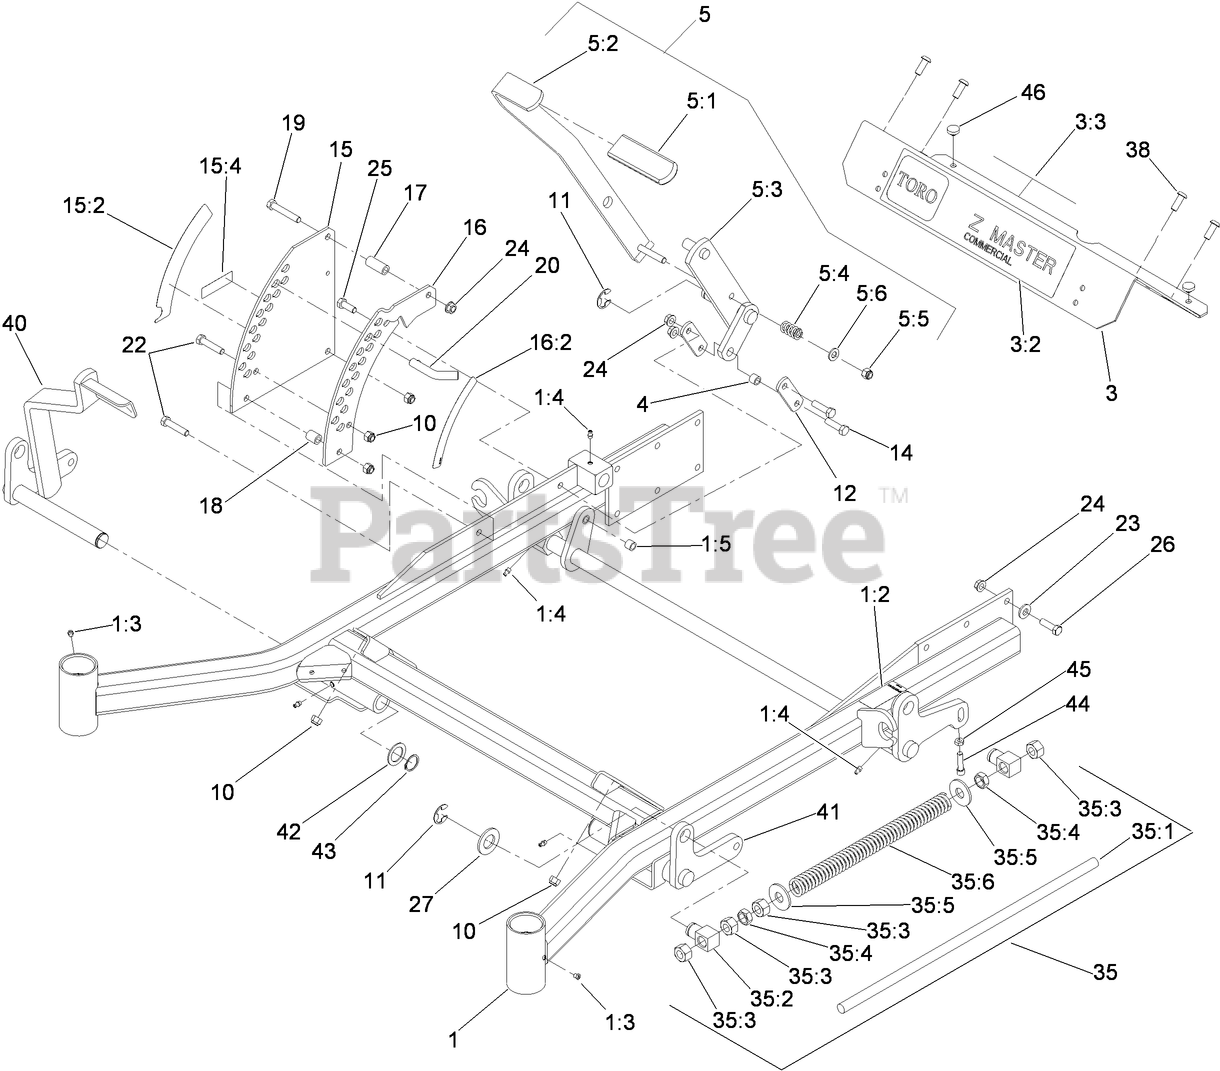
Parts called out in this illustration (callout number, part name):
1	Frame ASM
1:2	Decal-Brake, Parking
1:4	FITTING-GREASE
1:5	Bushing
3	FOOTREST
3:3	DECAL-WARNING
4	Bushing
5	DECK LIFT HANDLE ASM
5:1	GRIP-LEVER, LIFT
5:2	LEVER-LIFT
5:3	ARM-LIFT, DECK
5:4	SPRING-COMPRESSION
5:5	NUT-LOCK, NI
5:6	WASHER-FLAT
10	NUT-LOCK, NI
11	RING-RETAINING, EXT
12	ARM-LIFT, DECK
14	SCREW-HH
15	PLATE-HOC, OUTER
15:2	Decal-Height, Deck
15:4	DECAL-ARRESTER, SPARK
16	PLATE-HOC, INNER
16:2	Decal-Height, Deck
17	BUSHING-LEVER, LIFT
18	BUSHING-LEVER, LIFT
19	SCREW-HH
20	PIN-HOC
22	SCREW-HH
23	WASHER-BELLEVILLE
24	NUT-HHF, WHIZ
25	SCREW-HH
26	SCREW-HH
27	WASHER-FLAT
35	FRONT FRAME SPRING ASM
35:1	ROD-LIFT, DECK
35:2	SWIVEL-DECK MOUNT, REAR
35:3	NUT-HEX
35:4	NUT-JAM
35:5	WASHER-FLAT
35:6	SPRING-SUPPORT, DECK
38	SCREW-HSBH
40	LIFT-DECK, RH FRONT
41	LIFT-DECK, LH
42	WASHER-SPACER
43	RING-RETAINING
44	SCREW-HSH
45	NUT-JAM
46	BUMPER
